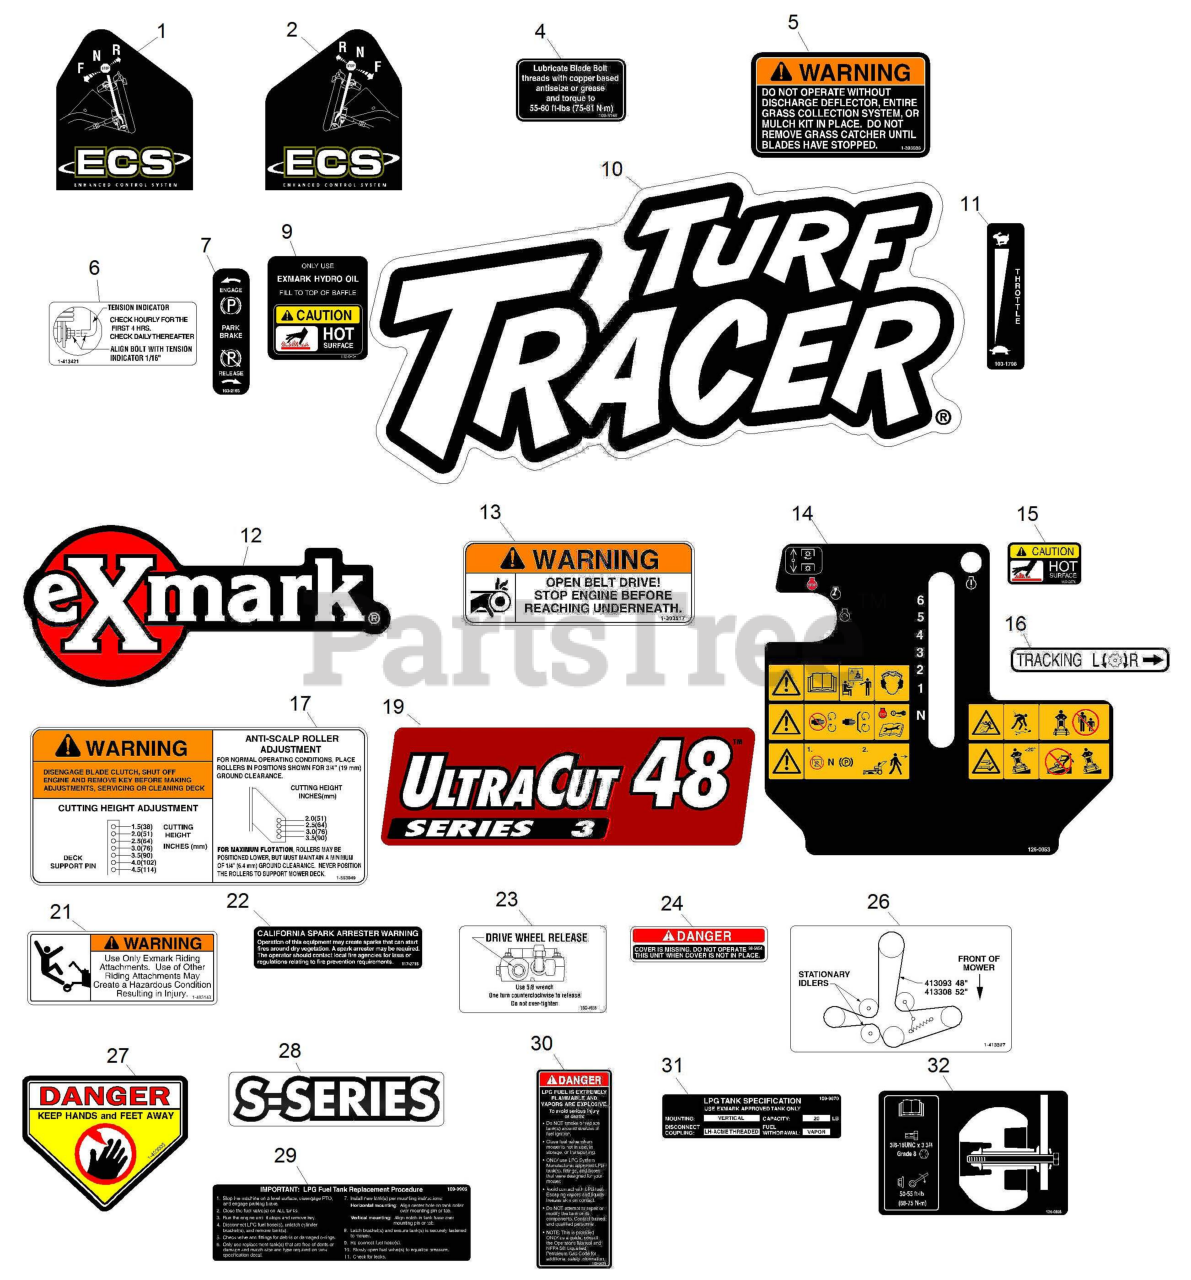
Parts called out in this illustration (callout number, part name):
1	DECAL,LH ECS INSTRUCTION
2	DECAL,RH ECS INSTRUCTION
4	DECAL,BOLT TORQUE
5	DECAL-WARNING, DISCHARGE
6	DECAL,INDICATOR
7	DECAL-BRAKE, PARK
9	DECAL-HYDRAULIC TANK
10	DECAL,TTH MODEL
11	DECAL,THROTTLE ONLY
12	DECAL,EXMARK LOGO
13	DECAL,BELT DRIVE
14	DECAL, CONSOLE TTS EFI
15	DECAL-CAUTION
16	DECAL,TRACKING ADJUST
17	DECAL,ANTI SCALP
19	DECAL-ULTRACUT 48 SERIES
21	DECAL,SULKY WARNING
22	DECAL-ARRESTER, SPARK
23	DECAL,DRIVE RELEASE
24	DECAL-COVER, MISSING
26	DECAL,BELT ROUTING
27	DECAL-DANGER
28	DECAL-S-SERIES
29	DECAL-TANK REPLACEMENT
30	DECAL-LPG WARNING
31	DECAL,LPG TANK SPEC VERTI
32	DECAL-ROLLER MOUNTING
